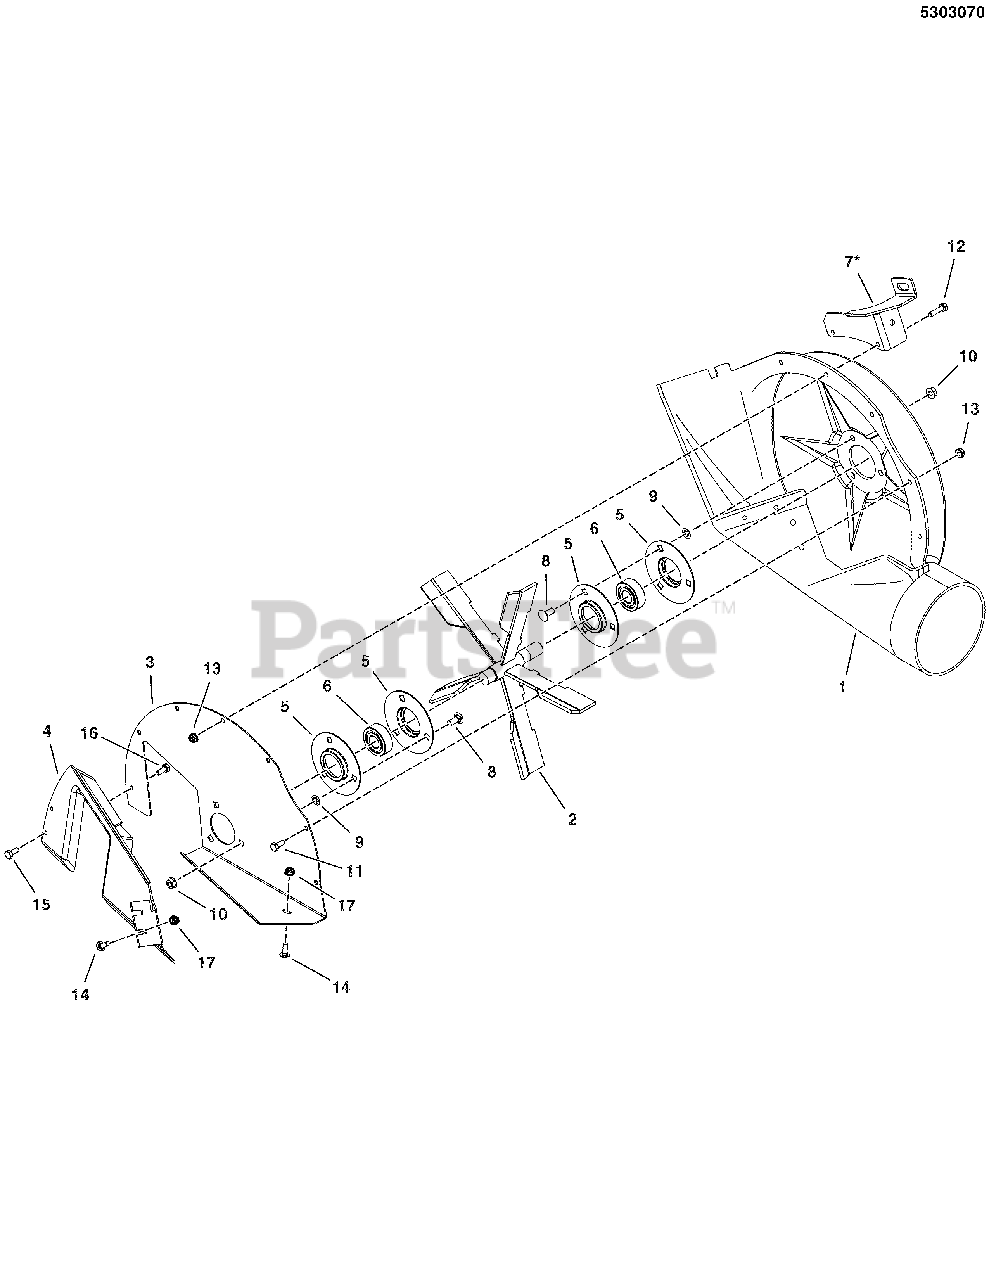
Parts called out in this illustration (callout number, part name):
1	HOUSING, FERRIS TURBO BLOWER
2	WELD, FAN ASSEMBLY, TURBO
3	PLATE, BLOWER TURBO - BLK
4	PLATE-COVER,BLACK POLY FOR LTH MDVS
5	RETAINER, BEARING CLEAR ZINC
6	BEARING-BALL 0.750ID 1.780OD 0.610LG
8	BOLT, 5/16-18 X 3/4, CARRIAGE
9	5/16 PUSH-ON NUT RETAINER, STL, CZ
10	NUT, 5/16-18 HEX SERRATED FLANGE
11	BOLT, 1/4-20 X 3/4 GD5 YZ
12	BOLT, 1/4-20 X 1" GD5 CZ
13	NUT, 1/4-20 HEX NYLOCK FLANGE (5025391)
14	BOLT, 1/4-20X.750, SQ
15	SCREW-HEX WSHR HD TAPTT 1/4-20X0.625 BLK
16	SCREW-HEX WSHR HD TAPTT 1/4-20X0.500 BLK
17	NUT, 1/4-20 HEX SERR. FLANGE
